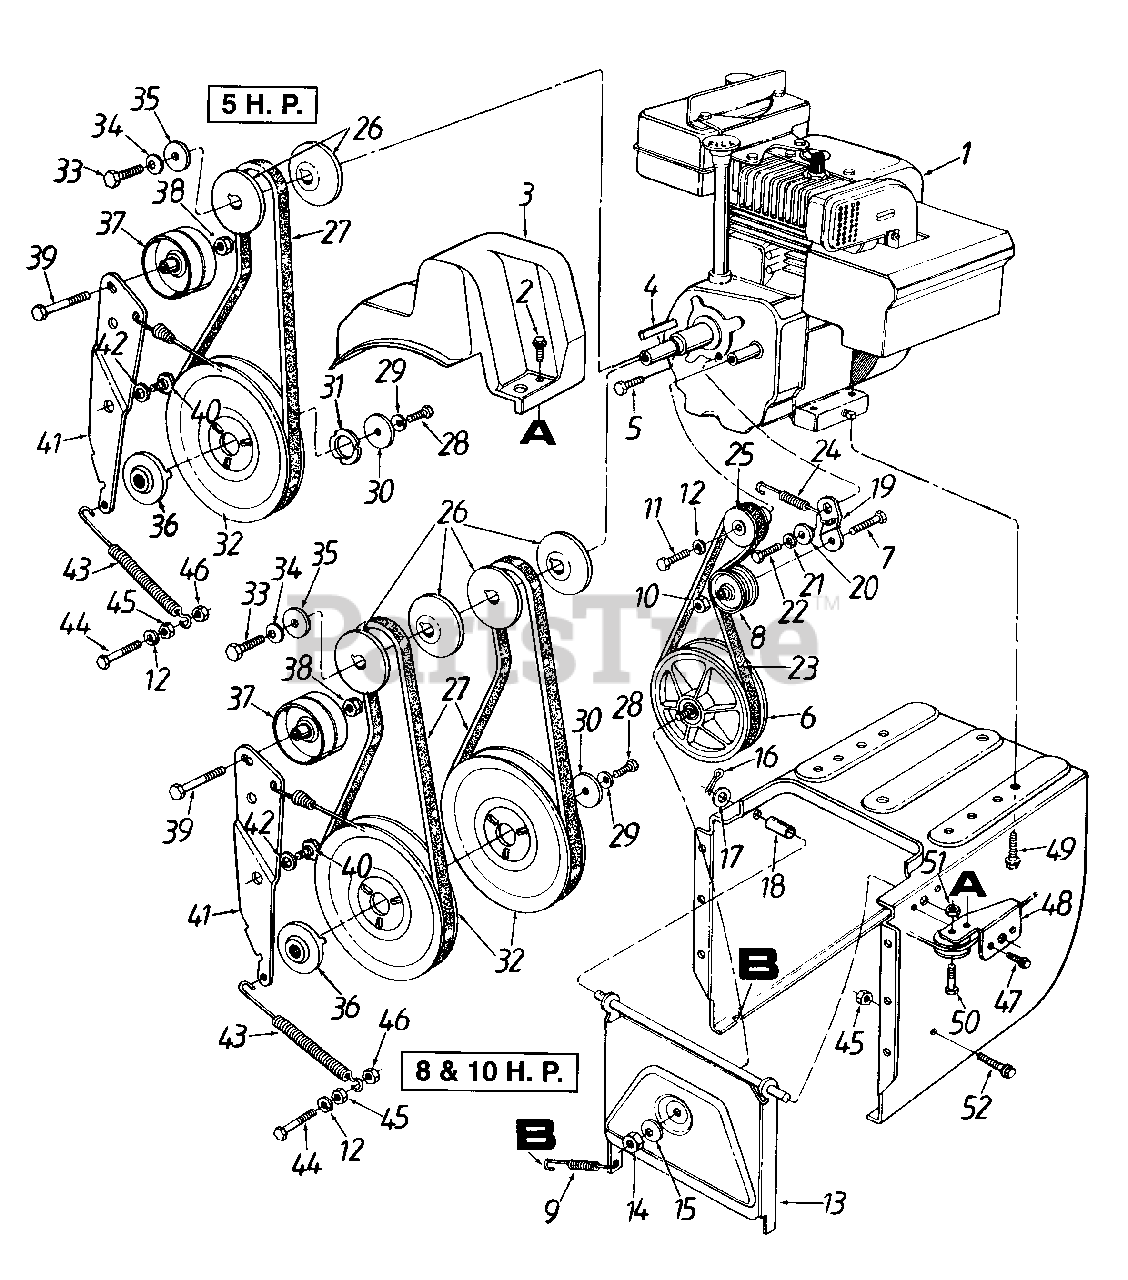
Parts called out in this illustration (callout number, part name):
1	Engine
2	Hex Wash. Hd. TT-Tap Scr. 1/4-20 x .5" Lg.
3	Belt Cover
4	Sq.-Key 3/16 x 1.5" Lg.
5	Hex Patch Bolt 5/16-24 x 1" Lg. (Gr. 5)
6	Friction Wheel Disc Ass'y.
7	Hex Bolt 3/8-16 x 1.25" Lg.
8	Fl-Idler 2.12" O.D.
9	Ext. Spring 2.5" Lg.
10	Hex Top L-Nut 3/8-16 Thd.
11	Hex Bolt 1/4-28 x .5" Lg.
12	L-Wash. 1/4" I.D.
15	Bell-Wash .38" I.D. x .88" O.D.
16	Cotter Pin 1/8" x .75" Lg.
17	Fl-Wash .531" I.D. x .93" O.D.
18	Spacer .508" I.D. x .75" 0 D.
19	Drive Clutch Idler Bracket
20	Shld. Spacer .5" Dia. x .27" Lg.
21	L-Wash. 5/16" I.D.
22	Hex Bolt 5/16-24 x 1" Lg.
23	"V"-Belt
24	Extension Spring
25	2" Dia. Pulley
26	3/8 "V"-Pulley Half
27	"V"-Belt
28	Hex Cap L-Bolt 5/16-24 x .75" Lg.
29	Bell-Wash 345" I.D. x .88" O.D.
30	Fl-Wash .34" I.D. x 1.5" O.D.
31	Brg. Retaining Washer
32	Auger Pulley
33	Hex Bolt 3/8-24 x .88" Lg.
34	Bell-Wash .39" I D. x 1.13" O.D.
35	Fl-Wash. 406" I.D. x 1.25" 0 D.
36	Adapter Pulley
37	Fl-Idler 2 75" 0 D
38	Hex Ins. L-Nut 3/8-24 Thd
39	Hex Bolt 3/8-24 x 1 5" Lg. (Gr. 5)
40	Shld. Bolt .625" Dia x .170" Lg.
42	Wave Wash .66" I.D. x 88"
43	Ext. Spring 3.6" Lg.
44	Hex Bolt 1/4-20 x .75" Lg. (Gr 5)
45	Hex Nut 1/4-20 Thd.
46	Hex L-Nut 1/4-20 Thd.
47	Torx Mach. AB-Tap Scr. 1/4 x 62" Lg.
50	Shld. Bolt 5/16" Dia. x .35" Lg.
51	Hex Jam Nut 1/4-20 Thd
52	Hex Wash. Hd. TT-Tap Scr. 1/4-20 x 1" Lg.
